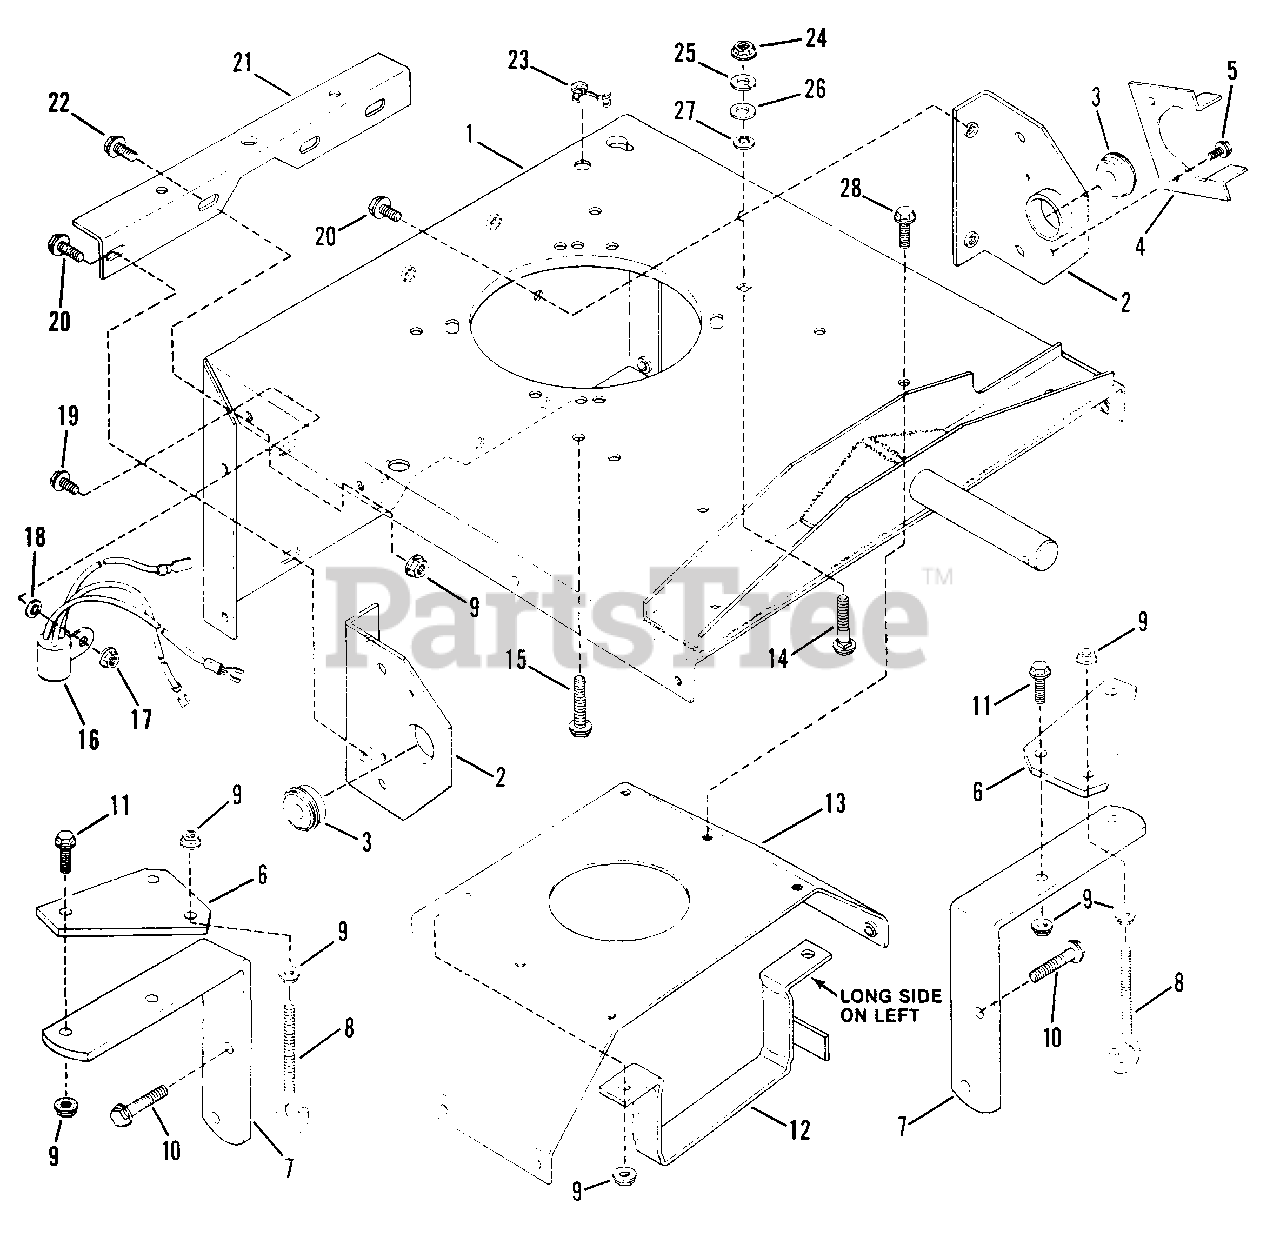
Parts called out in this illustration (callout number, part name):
1	FRAME, Rear
2	BRACKET, Support
3	BEARING
4	GUIDE, Belt
5	SCREW, 1/4-20 x 3/8" ST
6	PLATE, Deck Support
7	SUPPORT, Deck
8	HOOK, Chain
9	NUT, 5/16-18 HFL
10	SCREW, 5/16-18 x 1-1/2" HWHST
11	BOLT, 5/16-18 x 3/4" HFL
12	GUIDE, Belt
13	SUPPORT, Deck
14	BOLT, 5/16-18 x 1-1/2" SNC
15	BOLT, 5/16-18 x 1-1/2" HFL
16	INTERLOCK, B & S
17	NUT, 1/4-20 HFL
18	RETAINER, Bolt, 1/4"
19	SCREW, 1/4-20 x 1/2" HWHST
20	SCREW, 5/16-18 x 5/8" ST
21	DRAW-BAR
22	BOLT, 5/16-18 x 1/2" HFL
23	STRAIN RELIEF
24	NUT, 5/16-18 Hex
25	WASHER, 5/16 Split Lock
26	WASHER, 5/16 SAE
27	RETAINER, Bolt, 5/16"
28	SCREW, 5/16-18 x 3/4" ST
